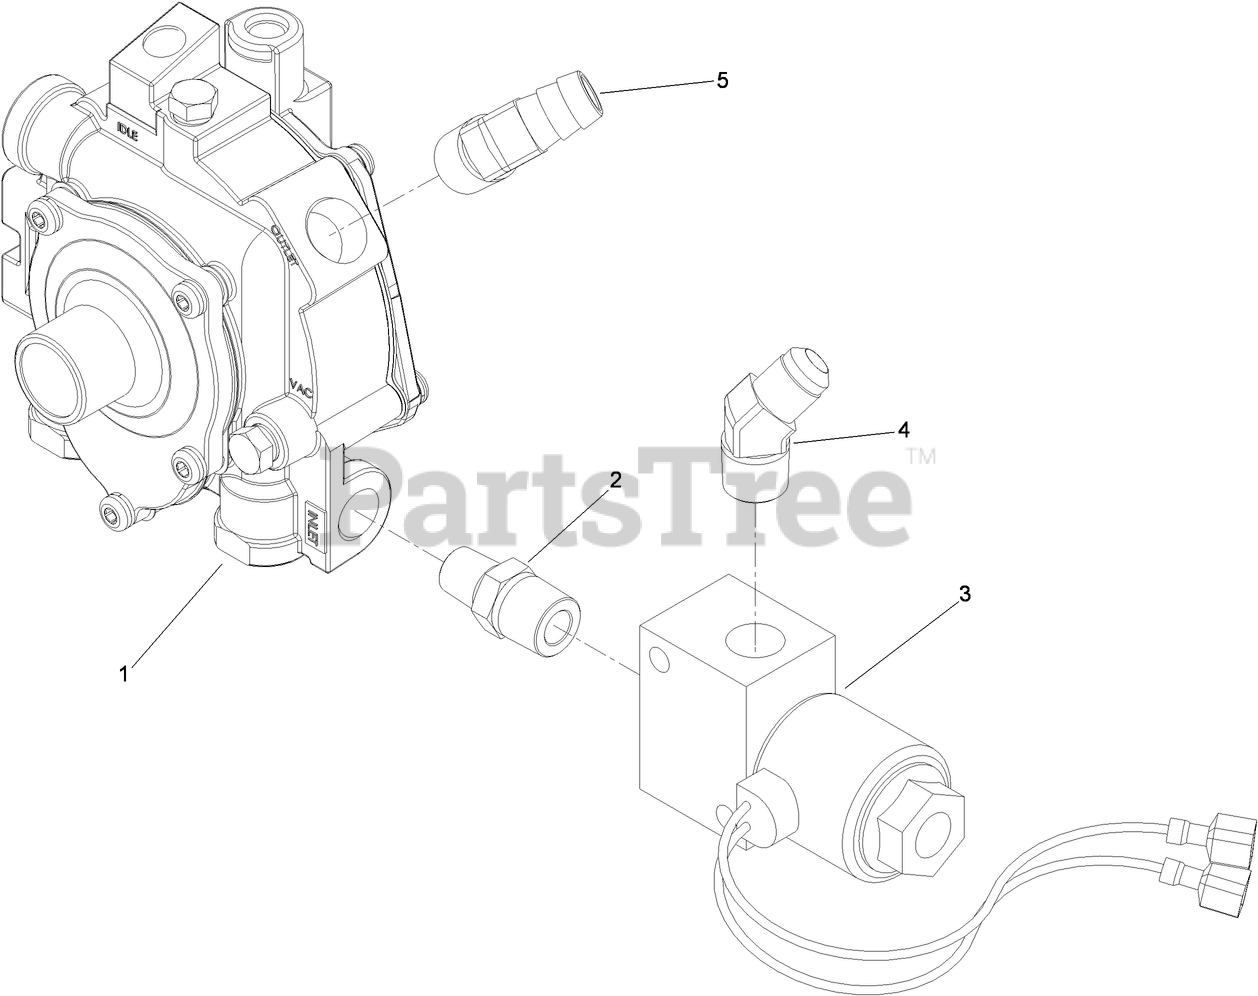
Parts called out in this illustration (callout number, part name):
1	REGULATOR-LPG, T60
2	COUPLING-PIPE, MALE
3	LPG SOLENOID VALVE ASM
